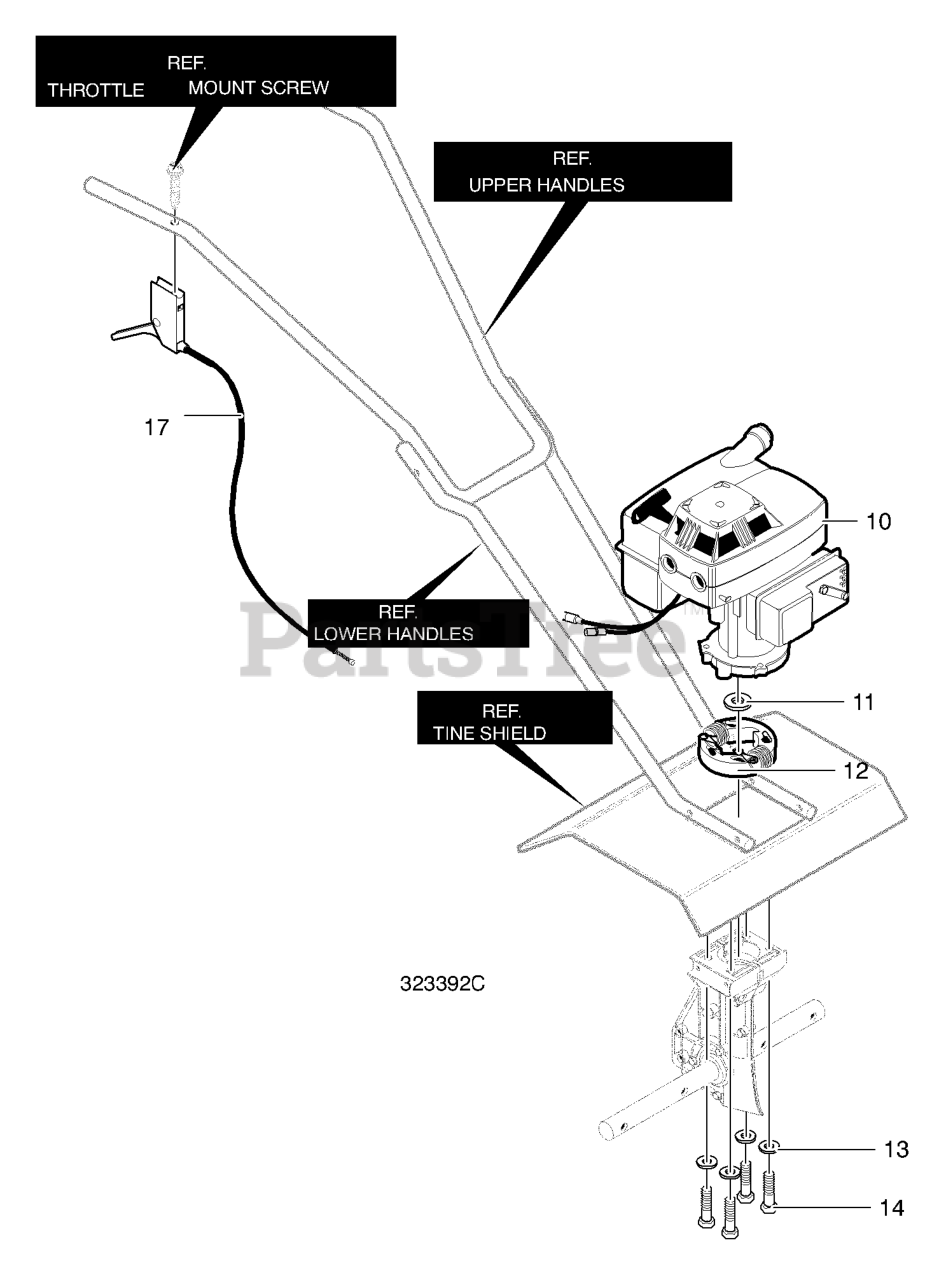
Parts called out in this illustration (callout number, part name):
10	Engine 2.0 HP
11	Flat washer
13	Washer, Regsptlk
14	Screw
17	Cable, Throttle
